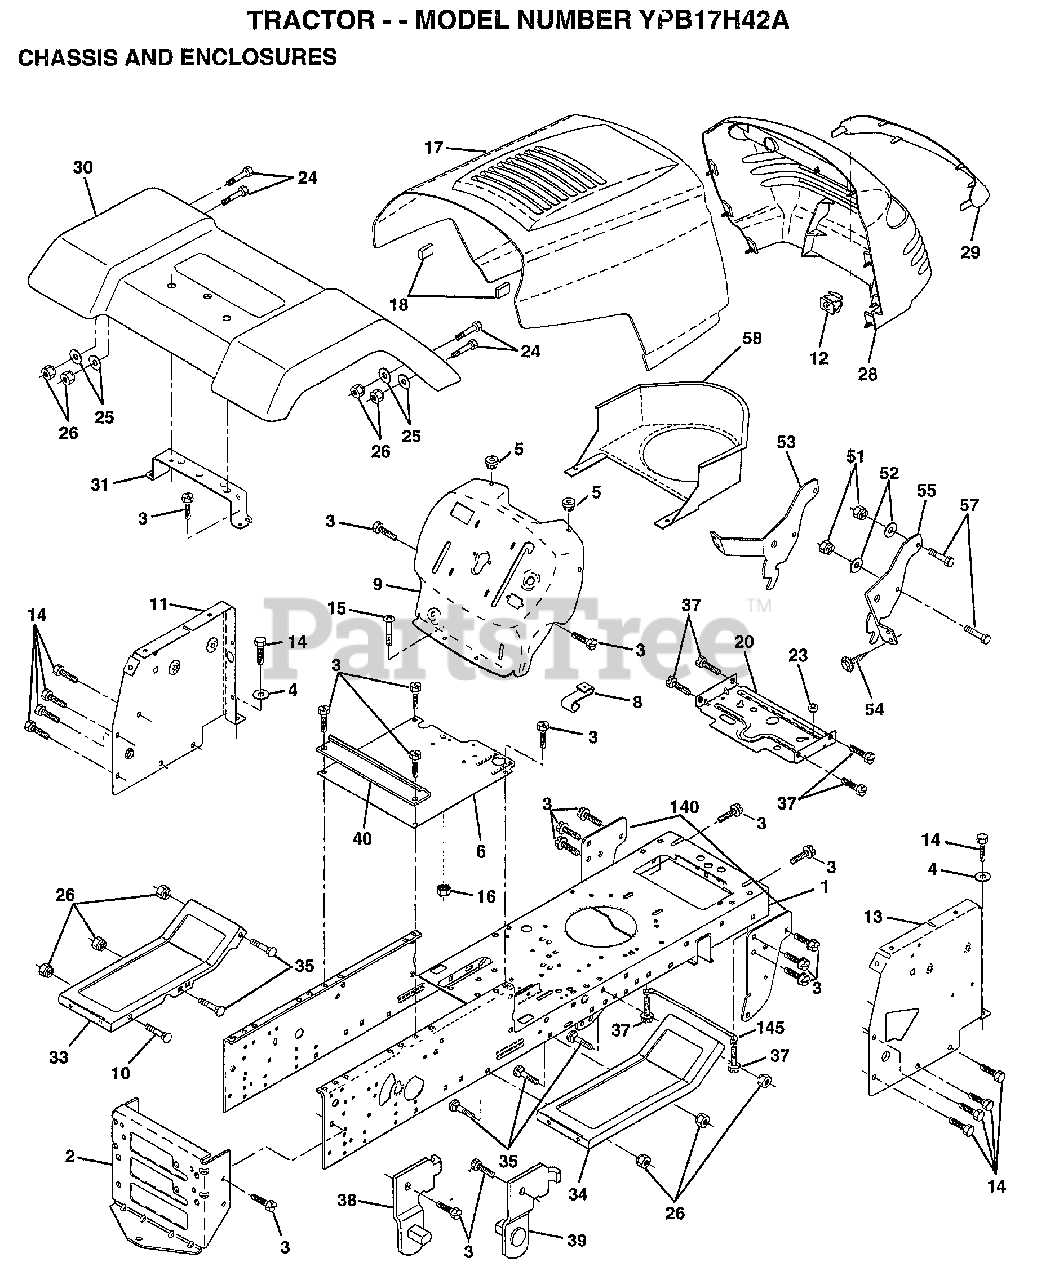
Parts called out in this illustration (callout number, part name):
1	CHASSIS.STAMPING
3	SCREW
4	WASHER
5	BUMPER-HOOD/DASH
6	SADDLE
8	CLIP.RETAINER
9	DASH.SILKSCREEN
11	"PANEL-DASH,LH"
12	CLIP.TINNERMAN
13	"PANEL-DASH,RH"
14	SCREW LT
15	SCREW
17	"HOOD W/TRIM,MS428"
20	"PLATE-MTG,BATT/FU"
24	BOLT
25	WASHER
26	NUT
28	GRILL
29	LENS.EURO.W/DECAL
30	FENDER.LTST.WLDMNT.W/SHIFT
31	BACK PLATE/BAFFLE
33	FOOTREST PNT LH
34	FOOTREST.RH.LT/GT
35	BOLT
37	SCREW LT
38	BRACKET ASM LH
39	BRACKET ASM RH
40	SPACER FENDER LT
51	NUT
52	WASHER
53	BRACKET.GRILLE.LH
54	SCREW.HEX.WS.HD
55	BRACKET.GRILLE.RH
58	AIR DUCT
140	BRKT SUSPENSION
145	"ROD POVOT,CHASSIS"
